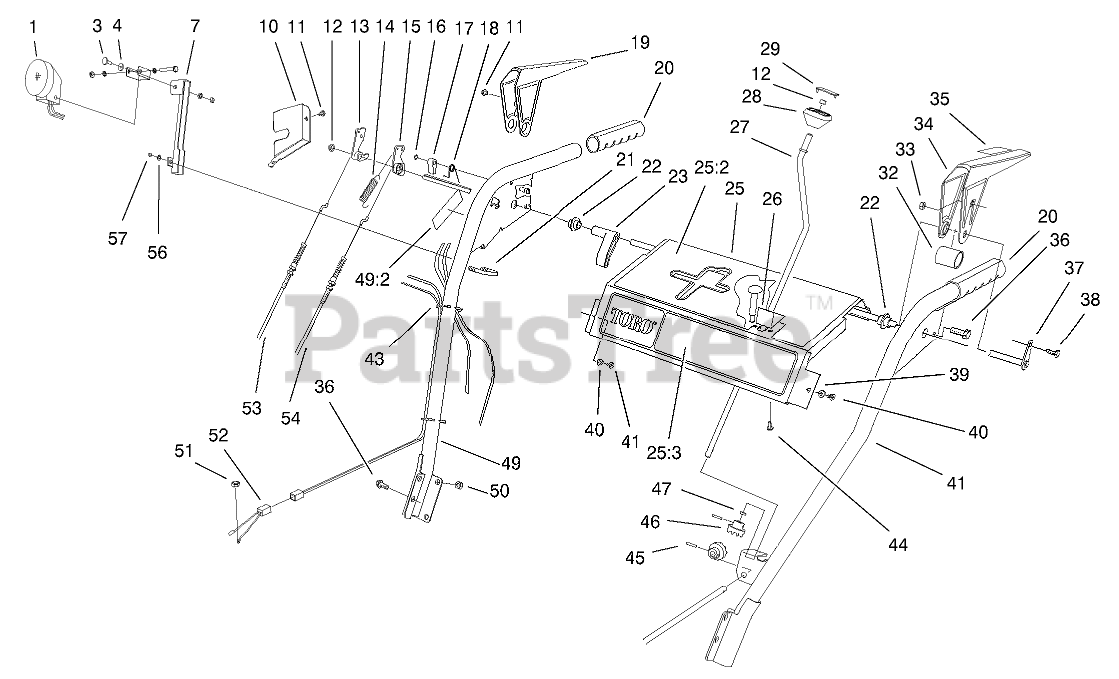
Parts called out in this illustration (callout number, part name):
1	Headlamp ASM (only on: 38559)
3	Screw-CARR (only on: 38559)
4	Washer-Flat (only on: 38559)
7	Mount-Light (only on: 38559)
10	COVER-LOCK, LEVER
11	SCREW-HH
12	RETAINER-PUSH ON
13	TANG-LOCKING
14	SPRING-EXTENSION
15	CAM-RELEASE
16	E-RING-RETAINER
17	LATCH-LOCKING
18	SPRING-TORSION
19	LEVER-TRACTION, RH
20	GRIP-HANDLE
21	U-Bolt (only on: 38559)
22	BUSHING-LEVER
23	LEVER-TRIP
25	Control Panel ASM (only on: 38560)
25	Control Panel ASM (only on: 38559)
25:2	Decal-Top, Panel (only on: 38560)
25:2	Decal-Control (only on: 38559)
25:3	Decal-Front Panel (only on: 38559)
25:3	Decal-Front Panel (only on: 38560)
26	PLATE-GUIDE
27	CRANK-ROD, CHUTE
28	KNOB-CONTROL, CHUTE
29	COVER-KNOB
32	SPACER-LEVER, TRACTION
33	NUT-LOCK, NI
34	LEVER-TRACTION, LH
35	Decal-Lever (only on: 38560)
36	SCREW-HWHTF
37	CROSS ROD ASM
38	SCREW-HWH
39	WASHER-FLAT
40	SCREW-HWHTF
41	LH HANDLE ASM
43	Tie-Cable (only on: 38560)
44	Screw (only on: 38560)
45	Pin-Spring (only on: 38560)
46	Gear-Universal (only on: 38560)
47	Washer-Rubber (only on: 38560)
49	Handle ASM (only on: 38560)
49	Handle ASM (only on: 38559)
49:2	Decal-Adjustment (only on: 38559)
49:2	Decal-Warning (only on: 38560)
50	Nut-Lock, NI (only on: 38560)
51	Nut-Hex (only on: 38559)
52	Wire ASM (only on: 38559)
53	Cable-Impeller (only on: 38560)
54	Cable-Traction (only on: 38560)
56	Washer-Flat (only on: 38559)
57	Nut-Lock (only on: 38559)
